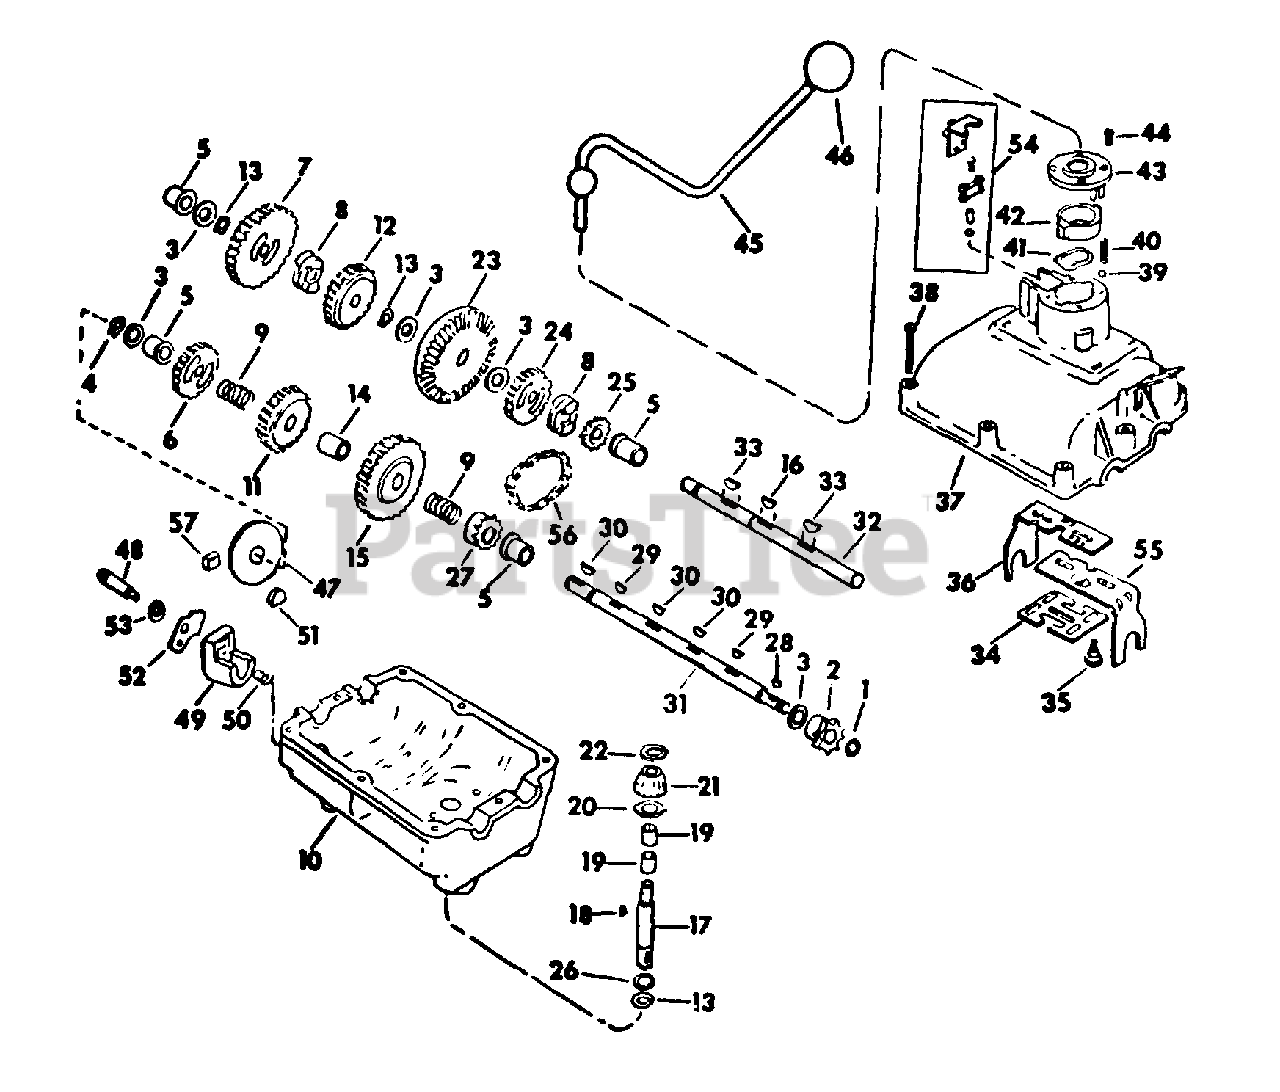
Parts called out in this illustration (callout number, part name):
1	RING, .461 INV EXT RET
2	SPROCKET, 8 T
3	WASHER, PLAIN .030
4	E-RING, 480 EXT RET
5	BEARING, FLANGE
6	GEAR, SPUR -20 T-
7	GEAR W/SPACER SPUR -30 T-
8	COLLAR, CLUTCH
9	SPRING, COMPRESSION
10	HOUSING, LOWER
11	GEAR. W/SPACER, SPUR -25 T-
12	GEAR W/SPACER, SPUR -25 T-
13	RING, .579 EXT RET
15	GEAR, SPUR -30 T-
16	KEY, 3/16 X 3/4 WOODRUFF 9
17	SHAFT KIT, INPUT
18	KEY, 3/32 X 1/2 WOODRUFF 2
19	BEARING, NEEDLE
20	WASHER, THRUST .093
21	PINION, BEVEL -16 T-
22	RING, .461 EXT RET
23	GEAR, BEVEL -42 T-
24	GEAR, SPUR -20 T-
25	SPROCKET, SPECIAL -12 T-
26	WASHER, 656 X 1.000 X .054 PLN
27	SPROCKET, SPECIAL -12 T-
28	KEY, WOODRUFF NO. 4 SPECIAL
29	KEY, 1/8 X 1/2 WOODRUFF 3
30	KEY, 3/16 X 5/8 WOODRUFF 61
31	SHAFT, OUTPUT
32	SHAFT W/RING, IH-269174-R1, DRIVE
33	KEY, HI-PRO SPECIAL
34	PLATE, LOCK-OUT
35	SCREW, SHOULDER
36	FORK, SHIFTER LH
37	HOUSING, UPPER
38	SCREW, TAPPING
39	BALL, 3/16 CR-STL DETENT
40	SPRING, DETENT
41	WASHER, WAVE
42	INSERT, NYLON
43	COVER, NYLON
44	SCREW, 10-24 X 1/2 C-Z CR-REC-PAN-HD TAP.
45	HANDLE ASSY. SHIFTER
46	KNOB, SHIFTER
48	BOLT, SHOULDER
49	KIT, BRAKE ASSY
50	SPRING, COMPRESSION
51	PUCK, FRICTION
52	LEVER ASSY, ACTUATING RH
53	WASHER, PLAIN .015
53	WASHER, PLAIN .006
54	KIT, SWITCH ASSY
55	FORK, SHIFTER RH
56	CHAIN, ROLLER
57	PUCK, FRICTION
